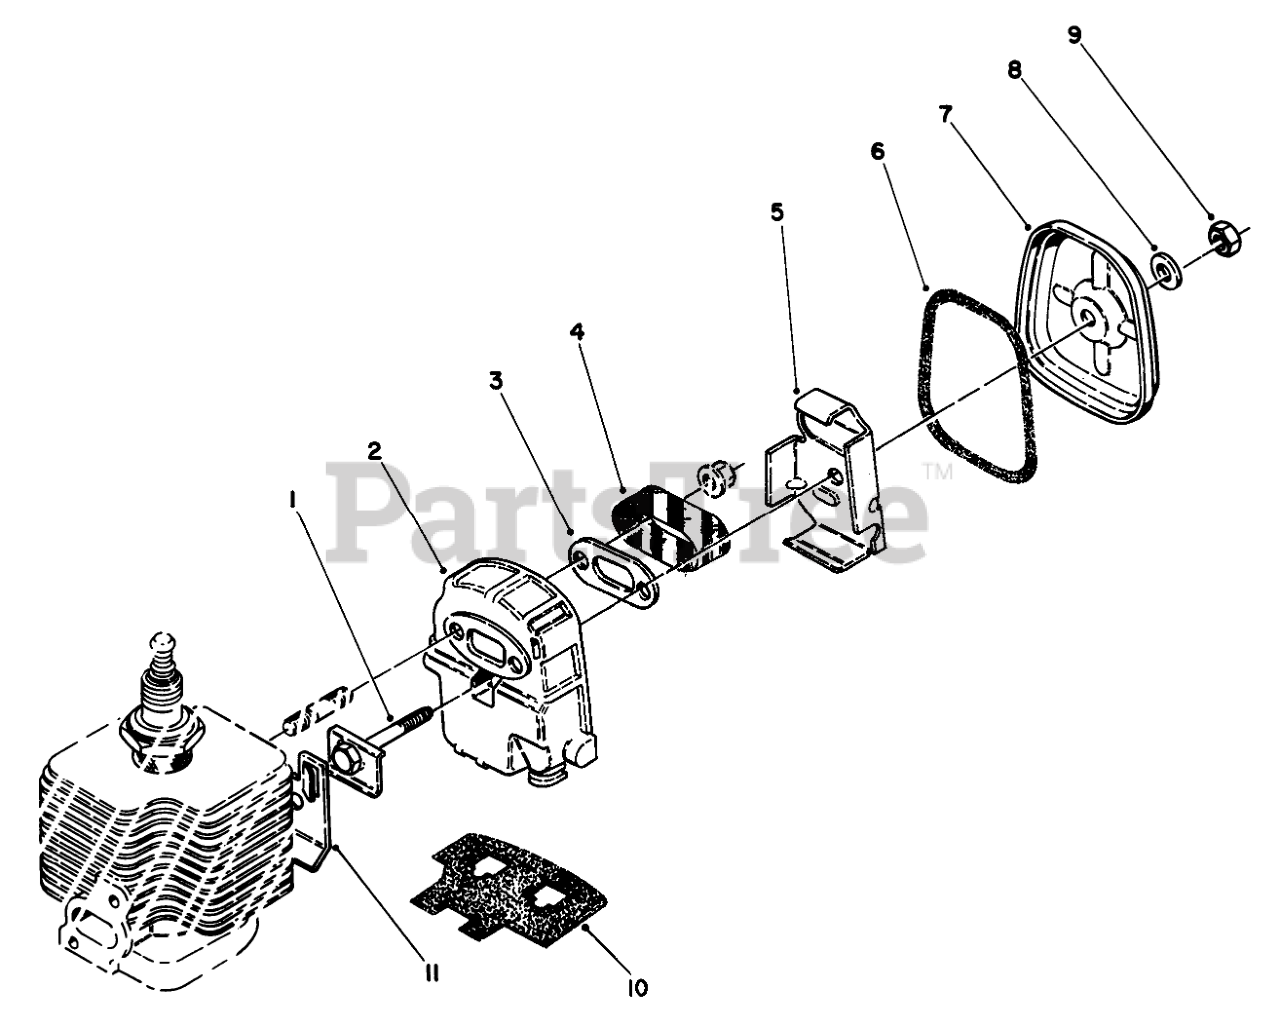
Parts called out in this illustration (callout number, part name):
2	Body-Muffler
3	PLATE
4	SCREEN
5	Plate
6	GASKET
7	MUFFLER LID
8	GASKET
10	GASKET
11	GASKET
